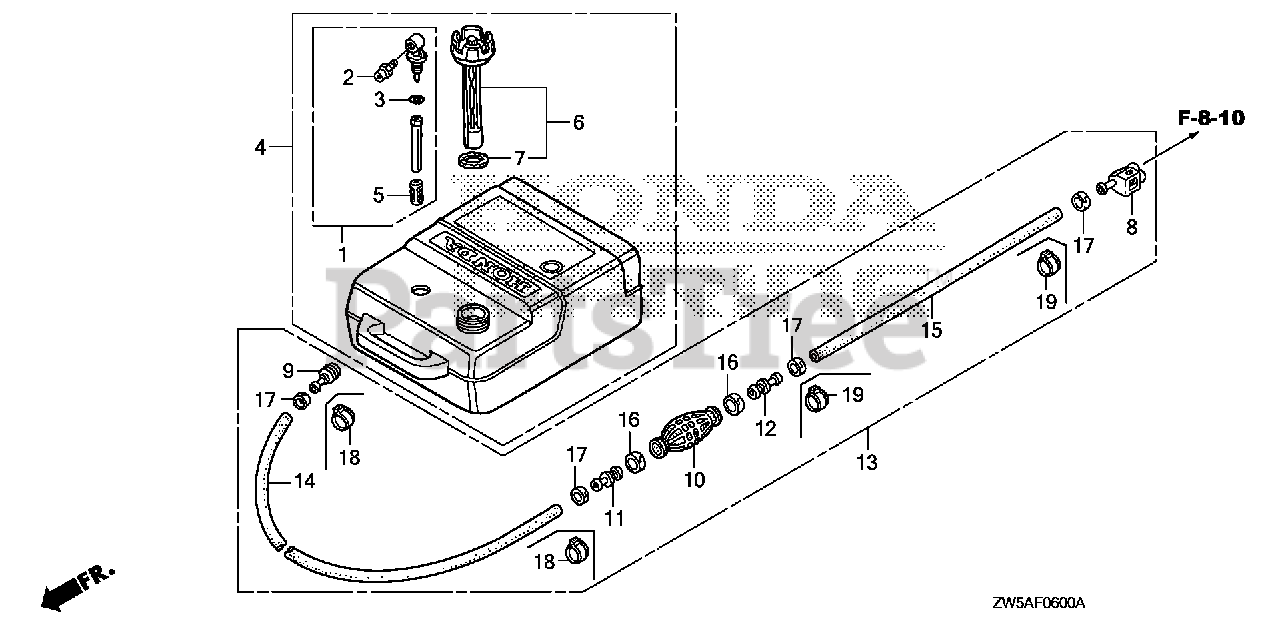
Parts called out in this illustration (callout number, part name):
1	JOINT ASSY., FUEL
2	FITTING, QUICK DISCONNECT
3	O-RING
4	TANK ASSY., FUEL
5	FILTER, FUEL
6	CAP, FUEL FILLER
7	GASKET, FUEL CAP
8	CONNECTOR ASSY., FUEL (A)
9	CONNECTOR, FUEL
10	BULB, PRIMER
11	VALVE, IN.
12	VALVE, OUTLET
13	TUBE ASSY., FUEL
13	TUBE ASSY., FUEL TANK
14	TUBE, FUEL LONG (7.3X2000)
15	TUBE, FUEL SHORT (6.3X500)
15	TUBE, FUEL SHORT
16	BAND, TUBE CLIP (20MM)
17	BAND, TUBE CLIP (12.5MM)
18	CLAMP, FUEL TUBE
19	CLAMP, FUEL TUBE
